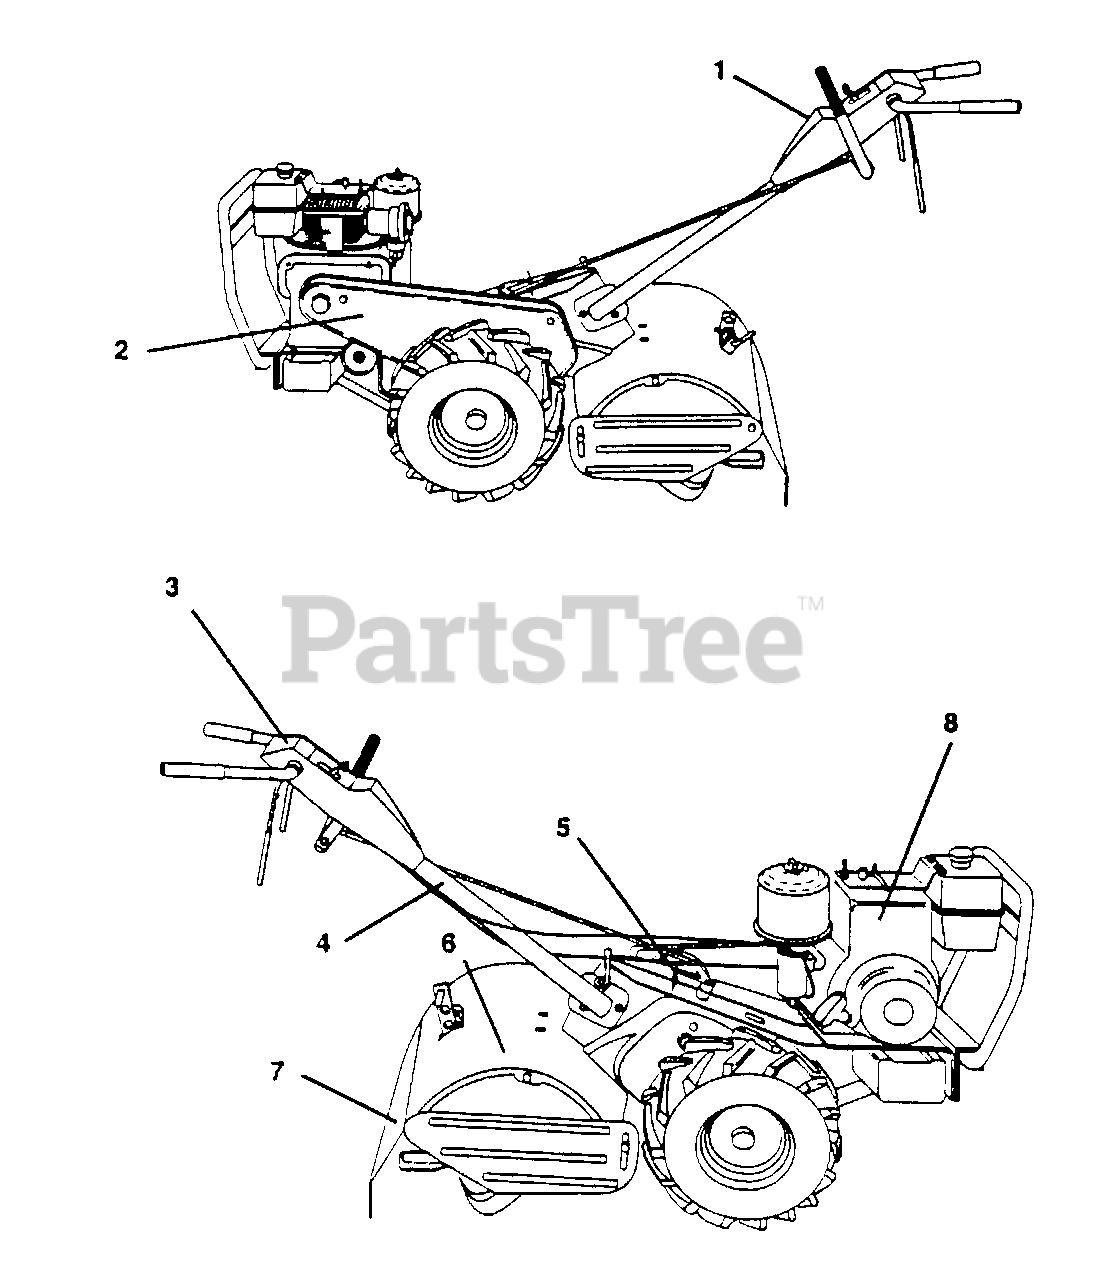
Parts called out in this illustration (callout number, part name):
1	Decal, Logo
2	Decal, Logo
3	Decal, Instruction, Tilling (AYP part number)
4	Decal, Hand Placement (AYP part number)
5	Decal, Shift Indicator (AYP part number)
6	Decal, Caution (AYP part number)
7	Decal, Warning, Rotating Tines (AYP part number)
8	Decal, Briggs & Statton (AYP part number)
